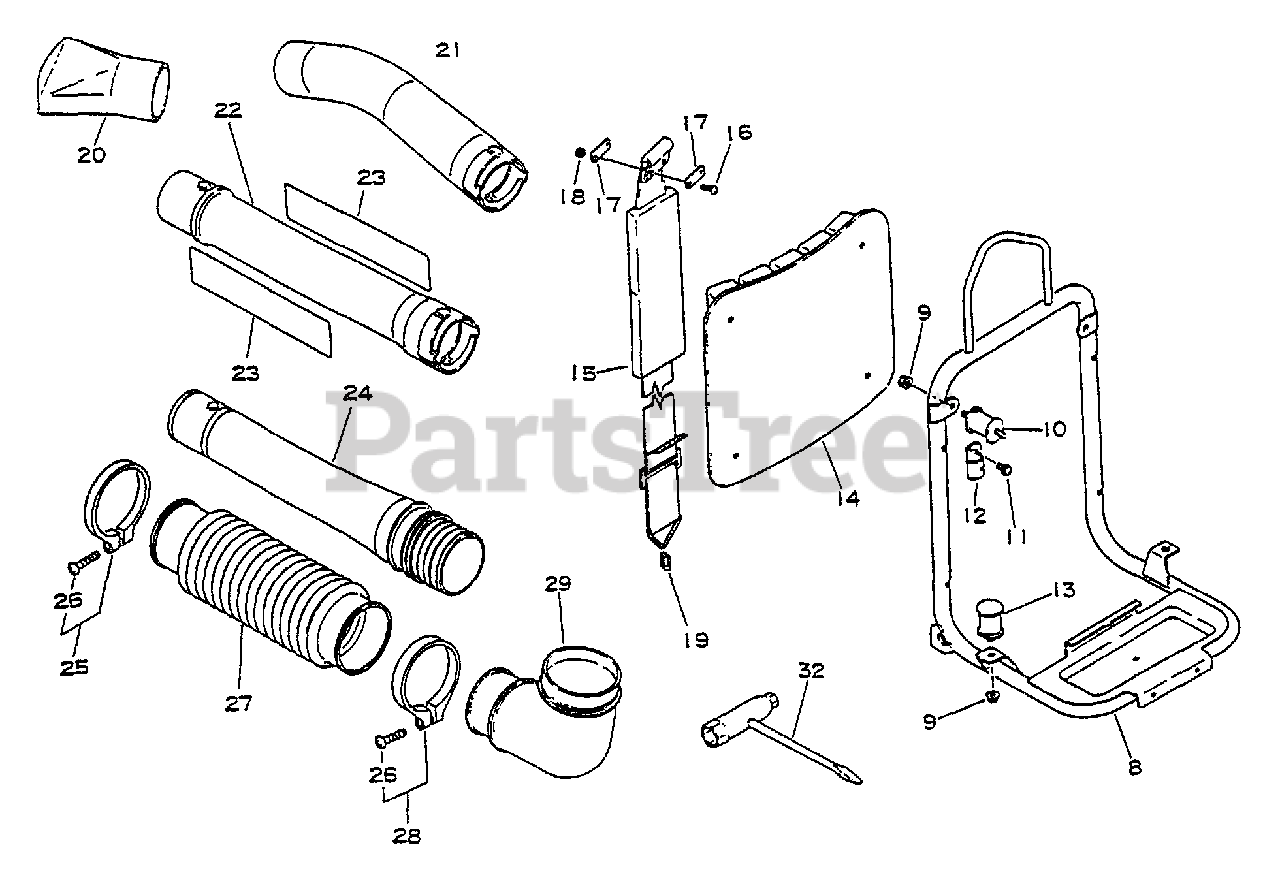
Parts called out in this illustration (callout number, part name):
8	FRAME, BACKPACK
9	NUT - 6 -- FLANGE
11	SCREW - 5X10
12	BRACKET, CUSHION
14	CUSHION, BACKPACK
15	BACKPACK STRAP ASSY
16	SCREW - 5X14
18	LOCKNUT - 5
19	RING, STRAP
20	NOZZLE - FAN HEAD
21	TUBE, BLOWER - CURVED
22	BLOWER TUBE KIT - STRAIGHT
23	LABEL - ECHO
24	TUBE, BLOWER - SWIVEL
25	CLAMP KIT
26	SCREW - 5X25
27	TUBE, BLOWER - FLEXIBLE
28	CLAMP KIT
29	TUBE, BLOWER - ELBOW
32	T-WRENCH - 10X19mm
